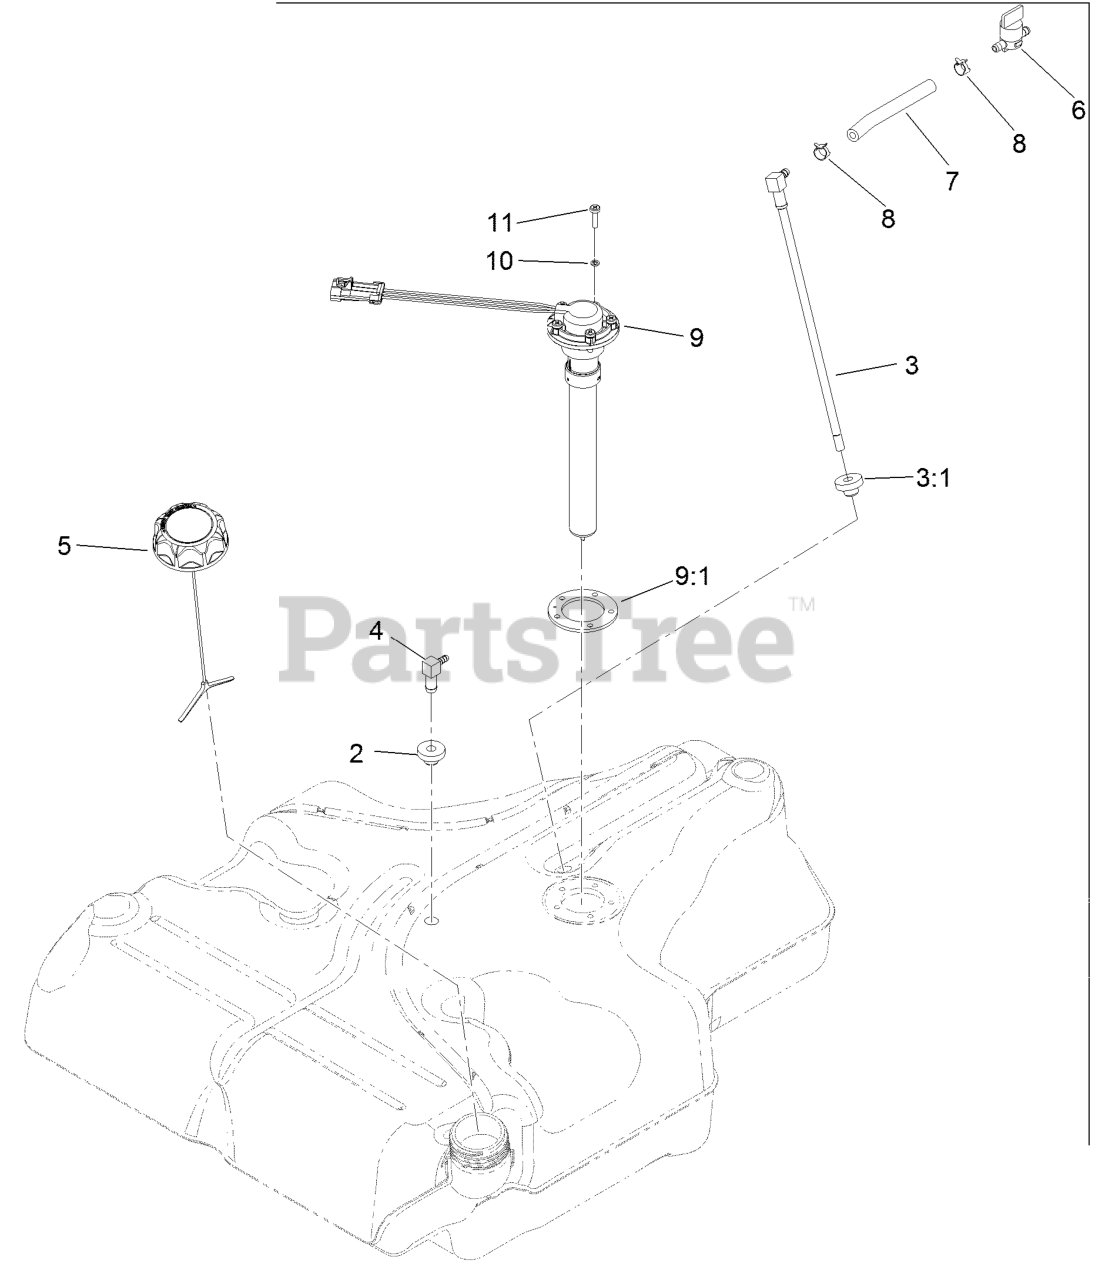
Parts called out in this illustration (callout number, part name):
2	BUSHING
3	FUEL LINE KIT (WITH GROMMET)
3:1	BUSHING
4	FITTING-90 ELBOW
6	VALVE-FUEL
7	HOSE-FUEL
8	CLAMP-HOSE
9:1	GASKET-SENDER, FUEL
10	WASHER-LOCK
11	SCREW-PAN
